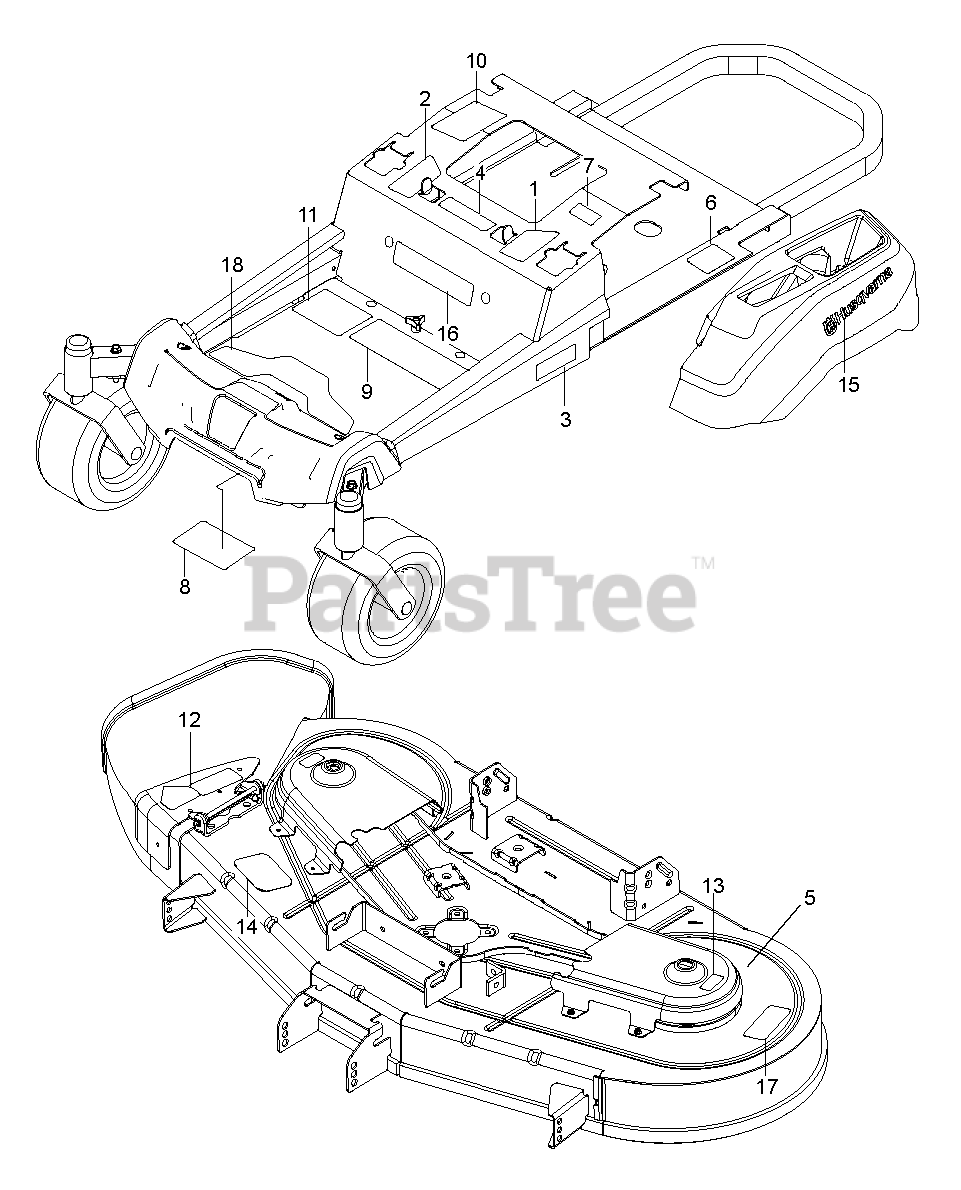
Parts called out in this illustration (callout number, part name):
1	DECAL.ZTR.RZ.THRTL/PRKBRK.V2.L
2	DECAL.ZTR.RZ.THRTL/PRKBRK.V2.R
3	DECAL ZTR SIDE RAIL GRAPHIC DE
4	EURO DECAL-BATTERY WARNIN6
5	DECAL DECK DECAL DECAL.DECK.WA
6	DECAL, DO NOT TOW
7	DECAL, EXITING MOWER
8	DECAL, SERVICE
9	DECAL ZTR WARNING DECAL DECAL.
10	DECAL.WARNING.CUST.RESP.E85.
11	DECAL.ZTR.STARTINSTRCT.CHOKE15
12	DECAL.TRACT/ZTR.DECKWARN.HUSQ
13	DECAL.DECK.CLEARCUT.NOSTEP
14	DECAL BELT ROUTING DECAL DECAL
15	DECAL.HUSQVARNA.210MM
16	DECAL ZTR BRAND GRAPHIC DECAL.
17	DECAL.54DECK.CLEARCUT.VER2.18
18	PAD.RZ.FOOTREST.PLATE
